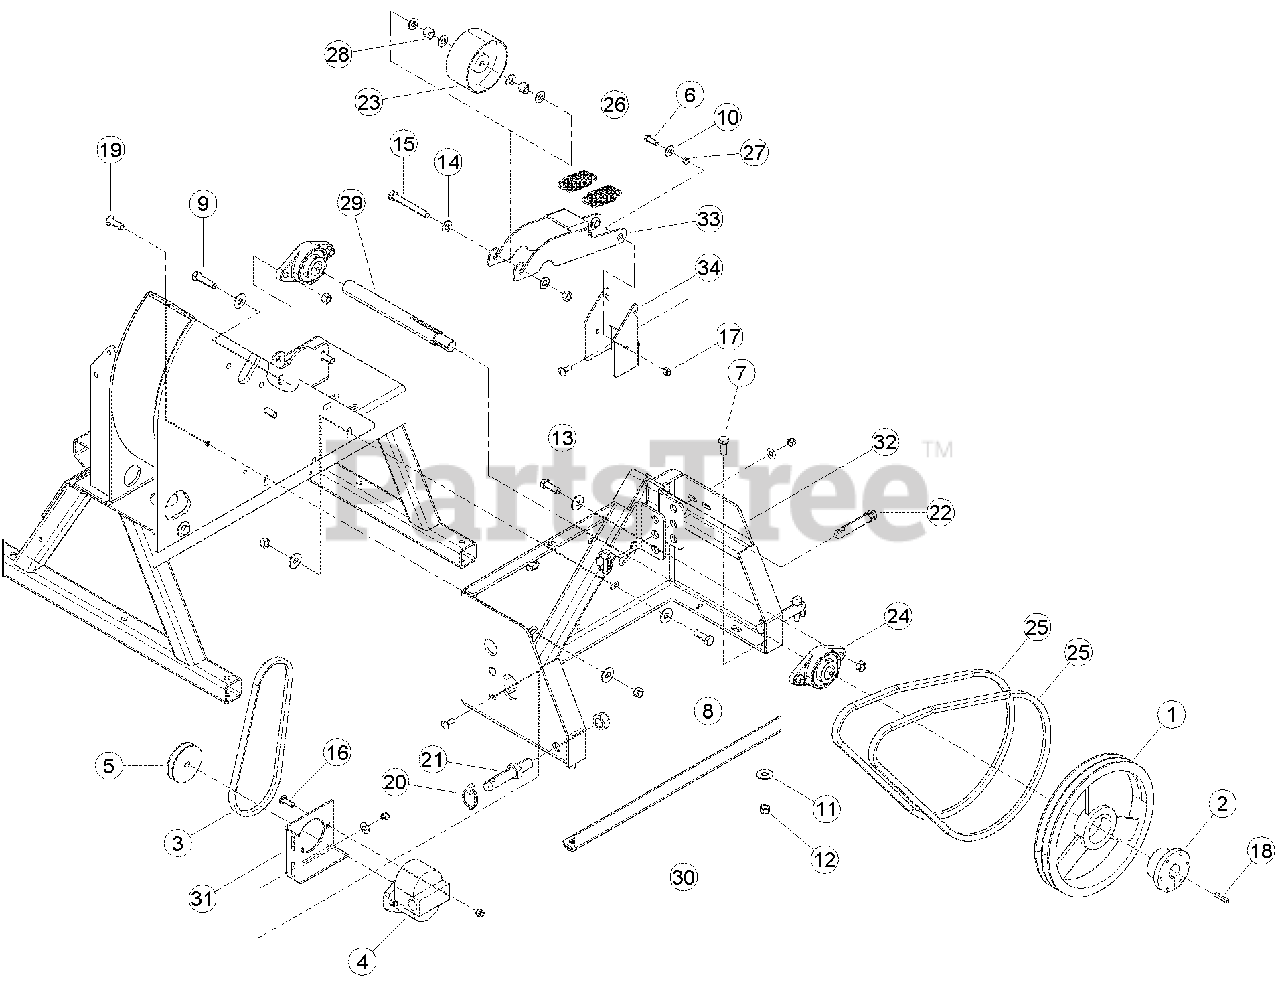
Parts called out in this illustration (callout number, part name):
1	SHEAVE, 2B12.4 SK
2	BUSHING, SK 1-1/4"
3	BELT, 4L350
4	PUMP, PTO HYDRAULIC FEED
5	PULLET, 3-1/2 X 5/8 A
6	BOLT, 3/8 X 1 HEX HD GR5 ZP
7	BOLT, 1/2 X 1-1/4 HEX HD GR5 ZP
8	BOLT, 1/2 X 1-1/2 HEX HD GR5 ZP
9	BOLT, 1/2 X 2 HEX HD GR5 ZP
10	WASHER, 3/8 FLAT ZP
11	WASHER, 1/2 FLAT ZP
12	NUT, 1/2 CENTERLOCK GRB ZP
13	BOLT, 3/8 X 1 CRG GR5 ZP
14	WASHER, 1/2 SAE FLAT ZP
15	BOLT 1/2 X 4 HEX HD GR5 ZP
16	BOLT, 3/8 X 1-1/4 CRG GR5 ZP
17	NUT, 3/8 NE NYLOCK ZP
18	KEY, 1/4 SQUARE X 1-1/2 LONG PLAIN
19	SCREW, 1/2 X 1-1/2 FLAT HD SKT
20	PIN, 7/16 X 1-3/4 LYNCH
21	PIN, LIFT ARM 7/8 X 5 LONG
22	PIN, TOP LINK 3/4 X 4-1/2 LONG
23	PULLEY, IDLER 5 X 2.50
24	BEARING, 1-1/4" 2 BOLT FLANGE
25	V-BELT, BX-56 SINGLE
26	SPRING, 1.25 OD. X 3.50 LG X .148 WD
27	SPACER, IDLER PIVOT
28	SPACER, .81 X .620
29	JACKSHAFT, PTO CHIPPER
30	BRACE, 3 PT. BOTTOM
31	WELDMENT, PUMP MOUNT
32	WELDMENT, CHIPPER HITCH
33	ARM, INSIDE IDLER
34	BRACKET, INSIDE IDLER ARM MOUNTING
